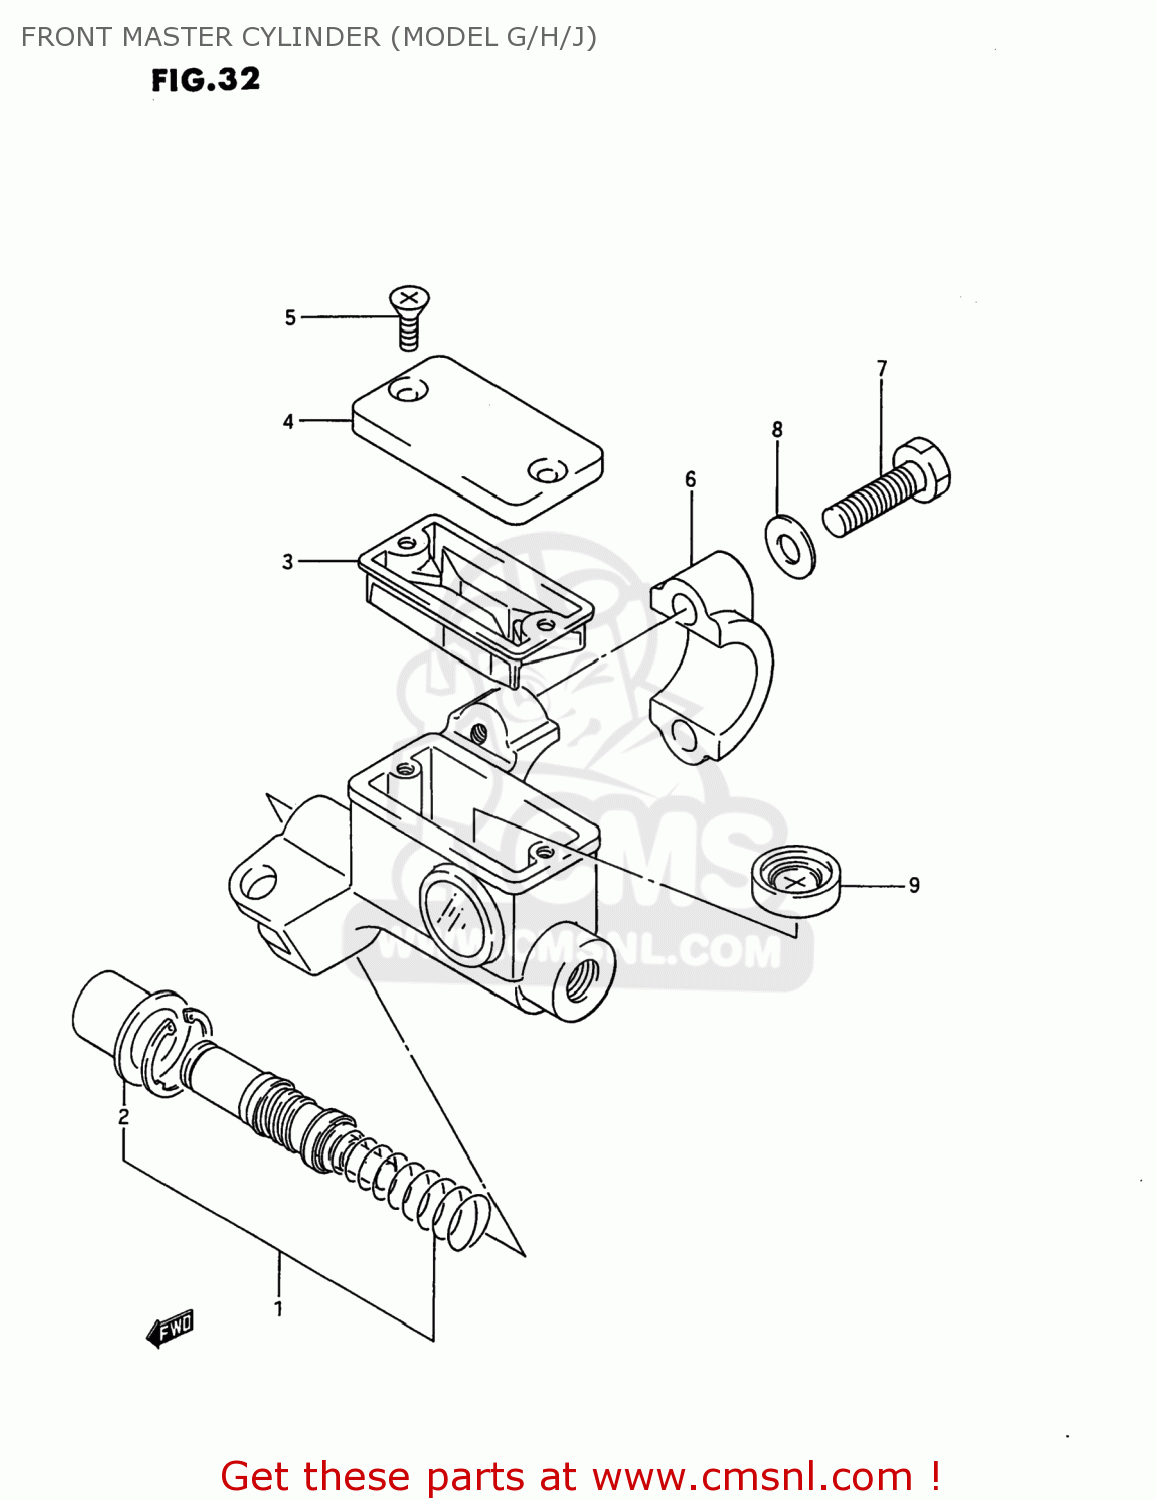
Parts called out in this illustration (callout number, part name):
1	PISTON & CUP SET
2	BOOT
3	DIAPHRAGM
4	CAP
5	SCREW
6	HOLDER,MASTER CYLINDER
7	BOLT
8	WASHER
9	SEPARATOR
